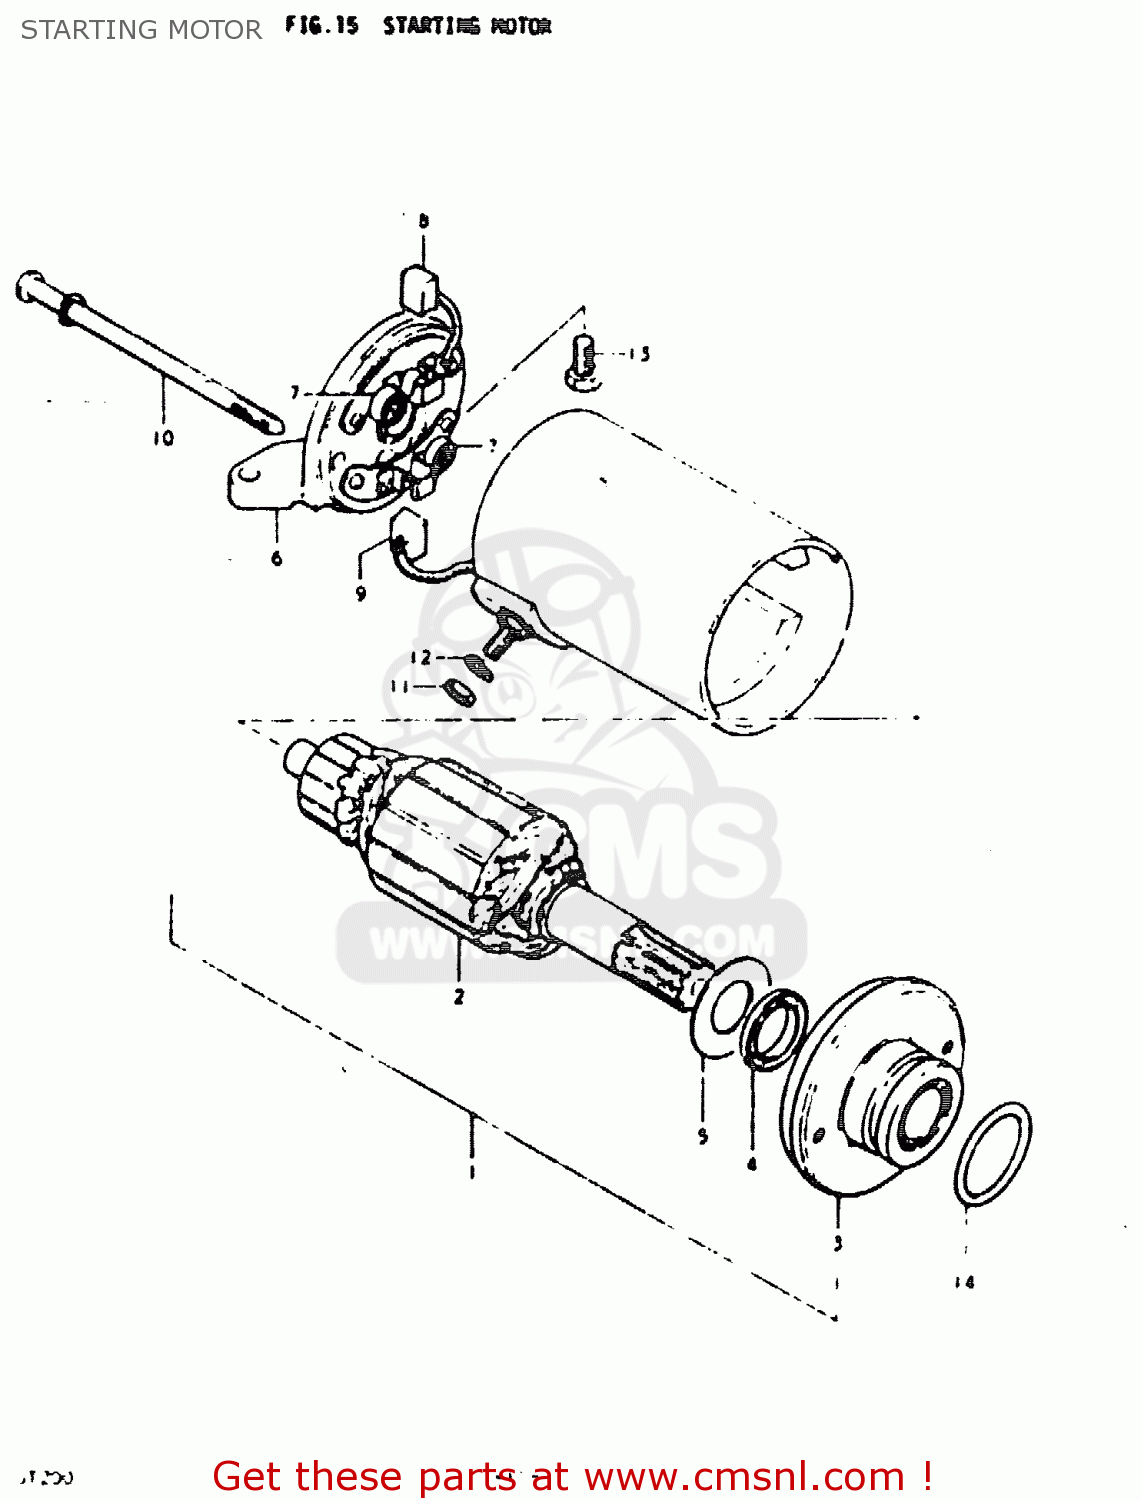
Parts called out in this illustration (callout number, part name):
1	MOTOR ASSY, STARTING
2	ARMATURE
3	HOUSING, DRIVE
4	SEAL,OIL
5	RING,SNAP
6	HOUSING, COMMUTATOR END
7	SPRING
8	BRUSH(-)
9	BRUSH TERMINAL SET
10	BOLT,STARTING MOTOR HOUSING
11	NUT
12	LOCK WASHER
13	BOLT
14	O RING(D:2,ID:24.5)
